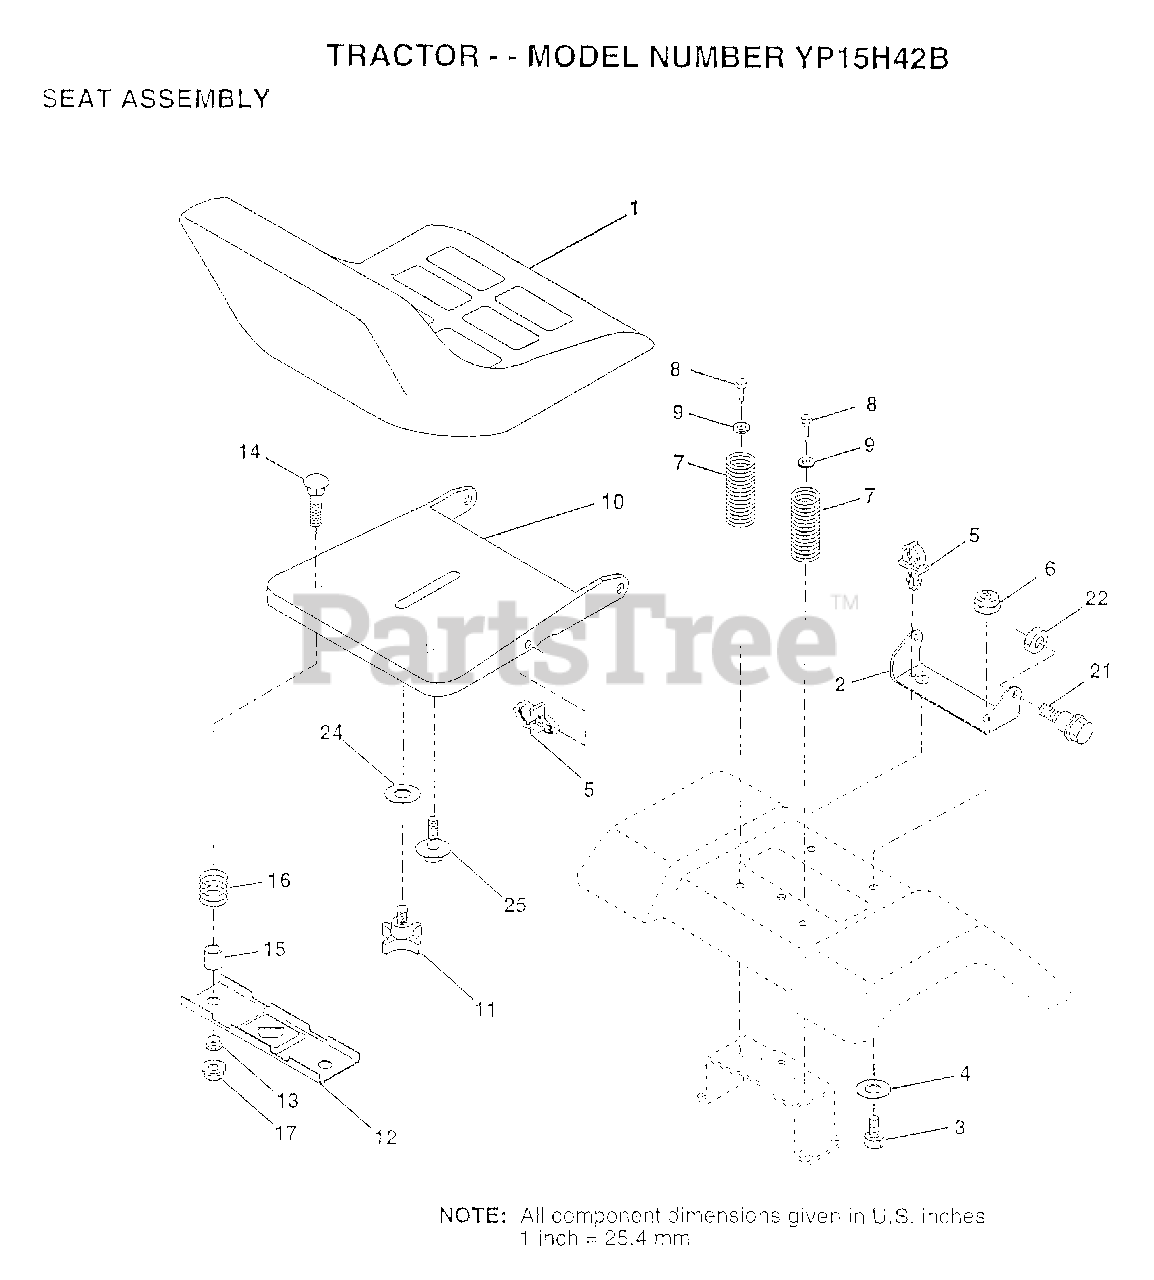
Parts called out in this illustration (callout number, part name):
1	SEAT.2400/1416.BK
2	BRACKET PVT SEAT
3	BOLT
4	WASHER PM
5	CLIP.PUSH-IN.HING
6	NUT
7	SPRING COMPRESSIO
8	SCREW GTV
9	WASHER
10	PAN-SEAT
11	"KNOB 1/2"" YT"
12	BRKT SWITCH
13	BUSHING
15	SPLIT SPACER
16	SPRING
21	"BOLT,SHOULDER"
22	NUT
24	WASHER
25	"BOLT,SHOULDER"
